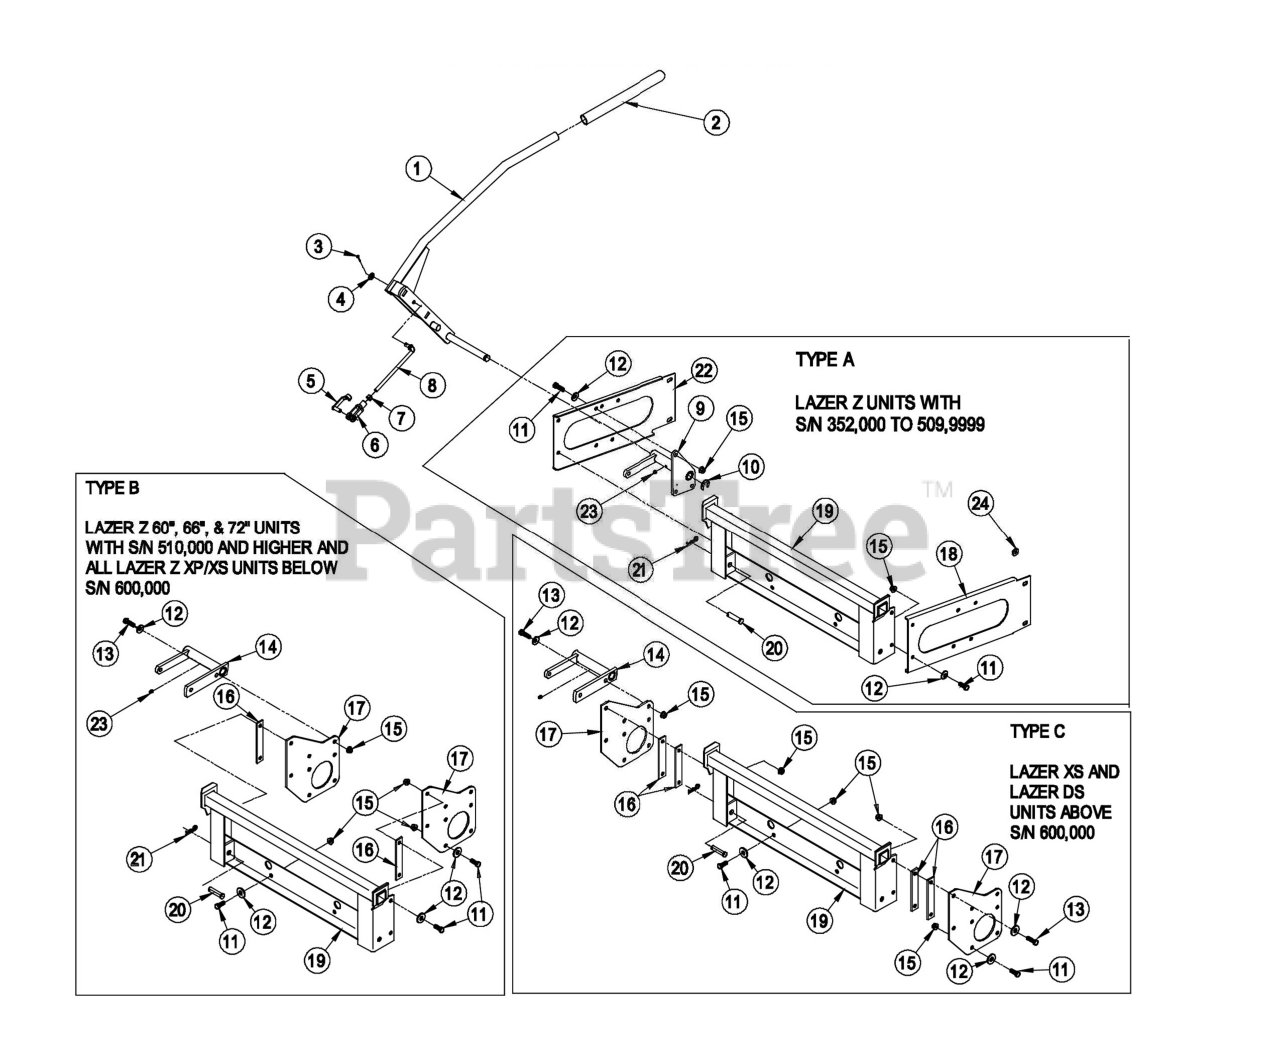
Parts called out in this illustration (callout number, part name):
1	HANDLE AND GRIP ASM
2	GRIP-HANDLE
3	PIN-COTTER
4	WASHER-FLAT
5	PIN-SPRING, CLEVIS
6	YOKE-LINKAGE, BRAKE
7	NUT-HEX
8	LINK-HANDLE
9	WLD, HANDLE MOUNT
11	SCREW-HH
12	WASHER-BELLEVILLE
13	SCREW-HH
14	WLD, HANDLE MOUNT - XP
15	NUT-HHF, WHIZ
17	PLATE-MOUNT, BAGGER
18	BRACKET-FRAME, RH
19	MOUNT-BAGGER
20	PIN-CLEVIS
21	PIN-COTTER
22	BRACKET-FRAME, LH
23	FITTING-GREASE
